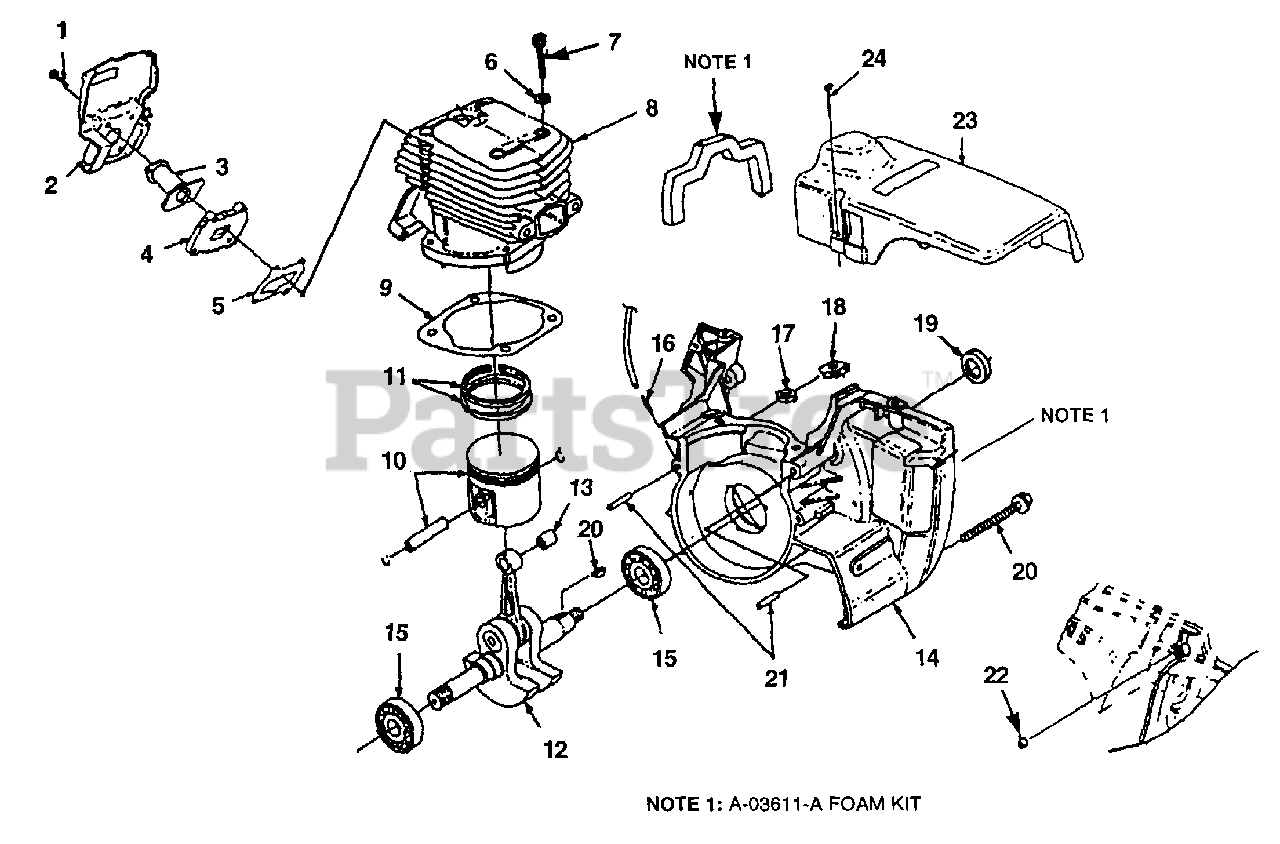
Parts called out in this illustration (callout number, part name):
1	SCREW - MACH. HEX HD (8-32 X 3/4")
2	BAFFLE - CYLINDER
3	BOOT - INTAKE
4	ADAPTER - INTAKE
5	GASKET - INTAKE
6	WASHER - CONICAL (#10)
7	SCREW - CAP SOCKET (10-24 X 1")
8	CYLINDER & PISTON (MATCHED)
9	GASKET - CYLINDER
10	PISTON & PIN ASSY.
11	PISTON RING
12	CRANKSHAFT & ROD
13	BEARING - NEEDLE
14	CRANKCASE ASSY
15	BEARING - BALL
16	FITTING - TUBE
17	NUT - LOCK HEX (10-24)
18	NUT - RETAINER
19	SEAL - SHAFT
20	SCREW - HEX SEMS (10-24 X 2")
21	PIN - DOWEL
23	COVER - CYLINDER
24	SCREW - CYLINDER COVER
